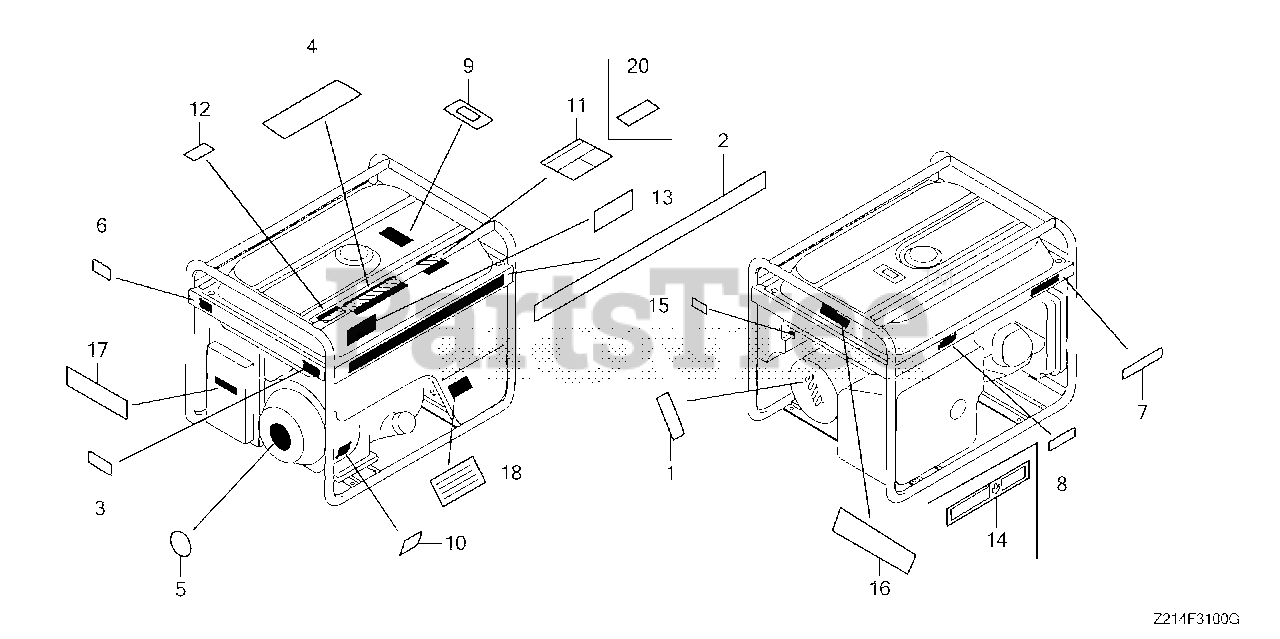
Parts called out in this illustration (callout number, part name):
1	MARK, VOLT
2	MARK, EMBLEM (EM6500SX)
4	MARK, CAUTION (E)
5	MARK, HONDA
6	MARK, CHOKE
7	MARK, HONDA
8	MARK, EX. CAUTION
9	PLATE, FUEL INDICATION
10	MARK, OIL CHECK
11	MARK, CPSC (CO CAUTION)
12	LABEL, WARNING
